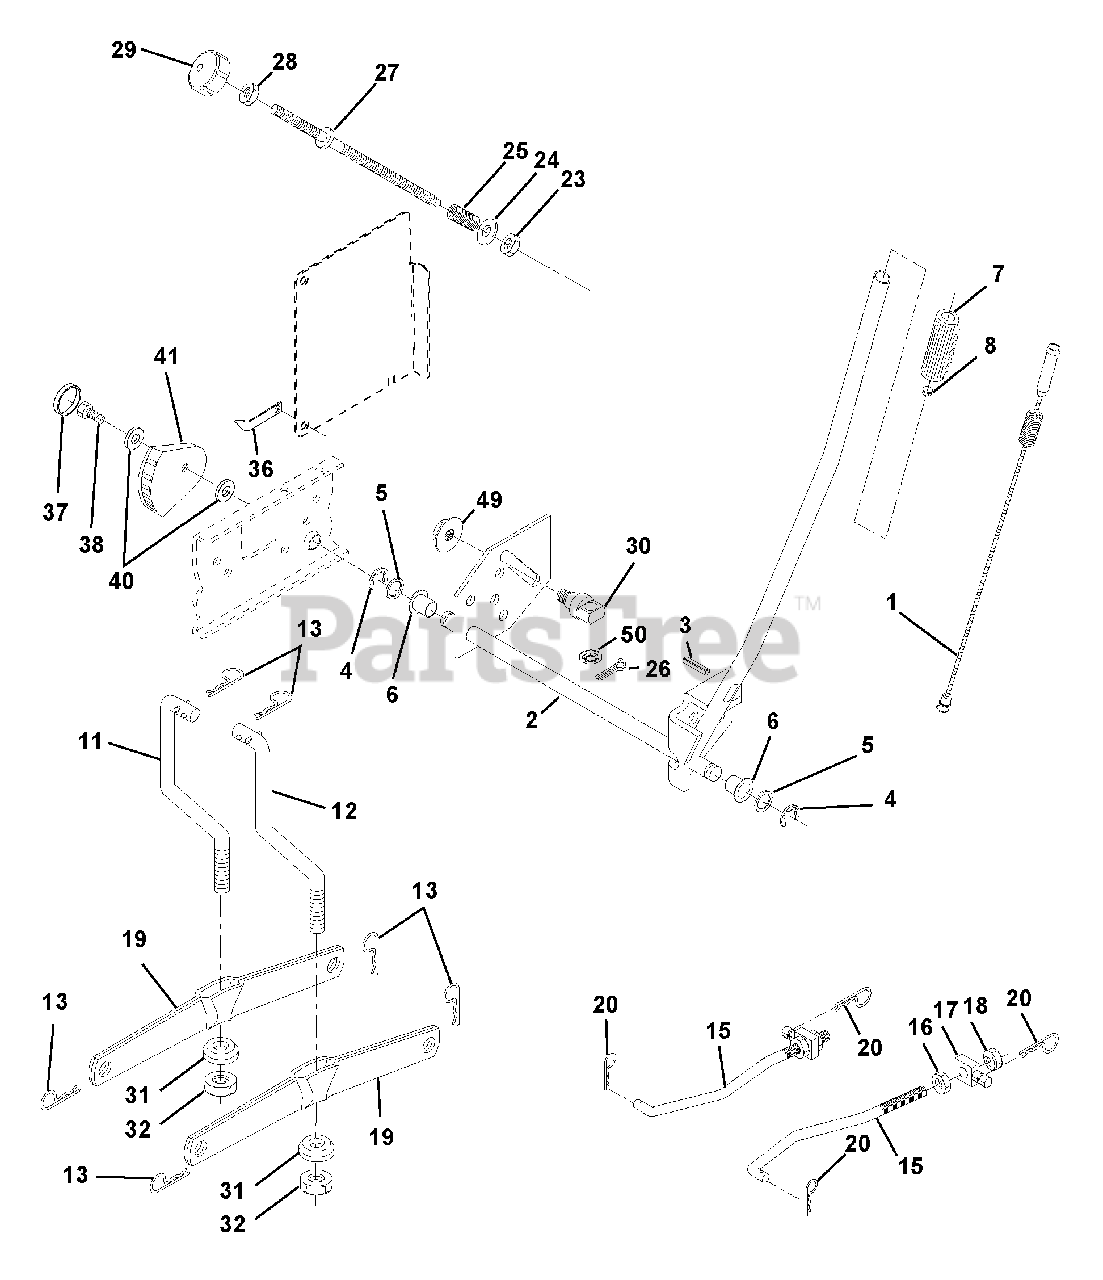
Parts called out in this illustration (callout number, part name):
1	Wire Asm Inner W/plunger
2	Shaft Asm Lift RH w/Inf
3	Pin Groove 1 500 Zinc
4	E Ring #5133-62
5	Washer 21/32 X 1 X 21 Ga
6	Bearing Nylon Blk 629 Id
7	Grip Handle Fluted Blk
8	Button Plunger Black
11	Link Lift LH Fixed Length
12	Link Lift RH Fixed Length
13	Retainer Spring
15	Link Front
16	Nut Jam Hex 1/2-13 Unc
17	Trunnion Blk Zinc
18	Nut Lock W/wsh 1/2-13unc
19	Arm Suspension Rear
20	Retainer Spring
23	Nut Special
24	Washer 13/32 X 5/8 X 16 Ga
25	Spring 2-1/8
26	Pin Cotter 3/32 X 1/2
27	Rod Adj Lift Zinc 7.49 Wrk Lg
28	Nut Hex Jam 3/8-16 Unc
29	Knob Inf 3/8-16 Unc Blk W/sym
30	Trunnion Infin Height
31	Bearing Pvt Lift Spherical
32	Nut Crownlock 3/8 - 24
36	Pointer Height Indicator
37	Plug Hole Blk 1.485/1.515 Dia.
38	Screw Thdrol 5/16-18 x 3/4
40	Washer 11/32 x 1-1/2 10 Ga.
41	Indicator Height STLT
49	Nut Hex Flange Lock
50	Nut Phos & Oil
